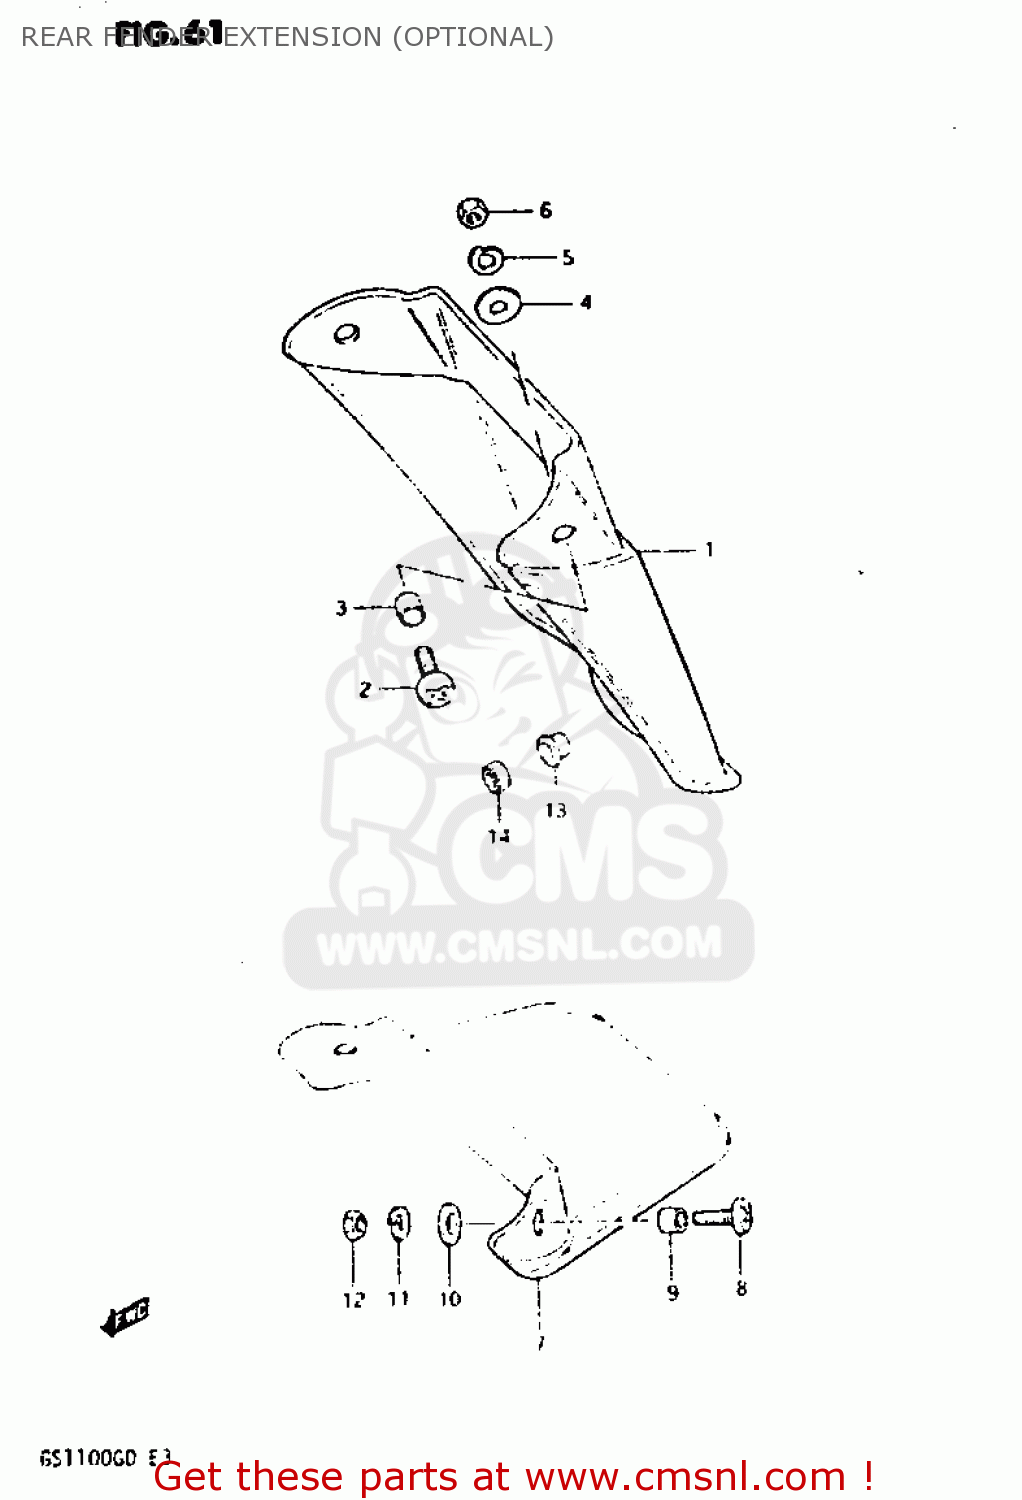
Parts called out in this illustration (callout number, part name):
1	EXTENSION,REAR FENDER
2	SCREW (6X15)
3	SPACER(6.2X8.3X5.7)
4	WASHER(6.5X18X1)
5	WASHER,LOCK
6	NUT
7	EXTENSION,REAR FENDER
8	SCREW (6X15)
9	SPACER(6.2X8.3X5.7)
10	WASHER(6.5X18X1)
11	WASHER,LOCK
12	NUT
13	WASHER
14	NUT
